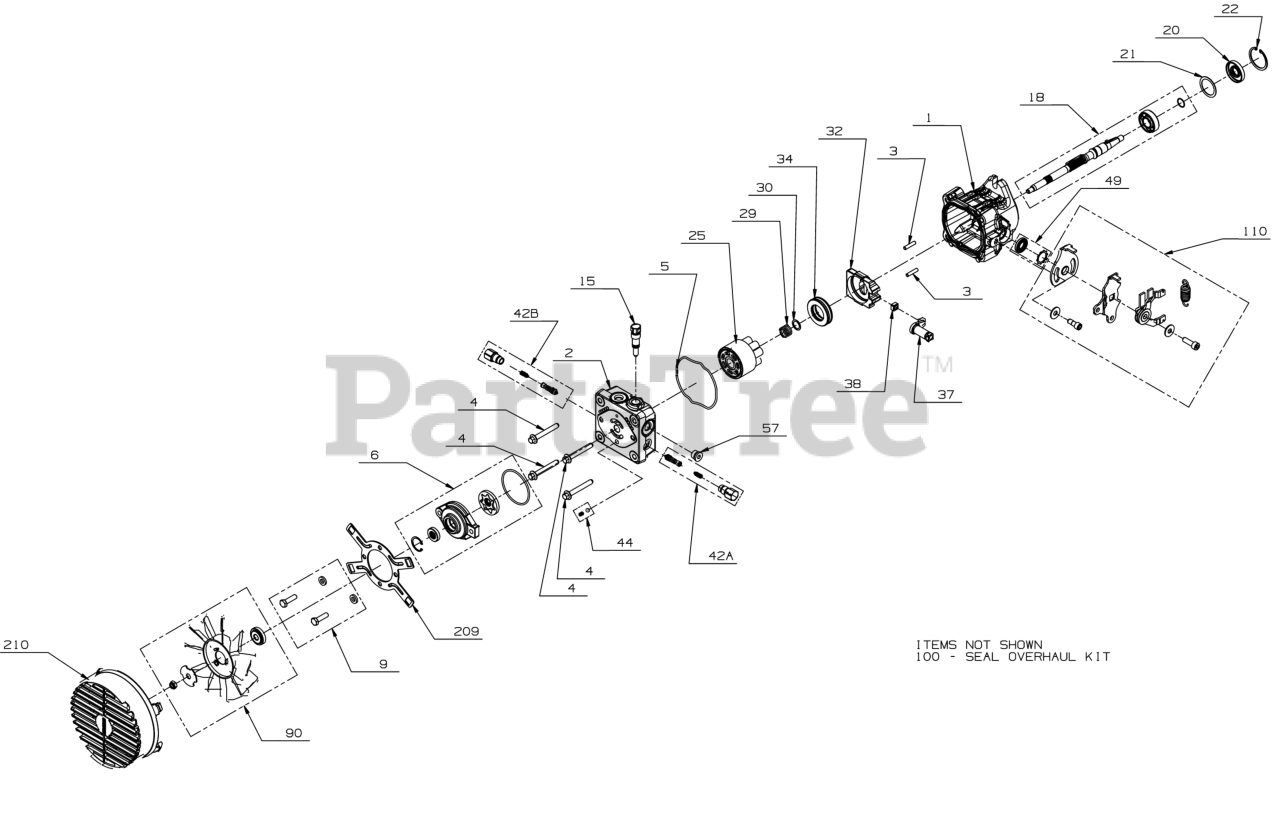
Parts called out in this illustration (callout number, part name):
1	KIT, HOUSING
4	SCREW-FLANGE HEAD
5	O-RING PMP HOUSING
6	PUMP ASSEMBLY-CHARGE
9	BOLT KIT-CHARGE PU
15	VALVE KIT-BYPASS
18	SHAFT KIT-PUMP
21	WASHER 1.23X1.56X
22	RETAINING RING
25	BLOCK KIT-CYLINDER
29	SPRING-BLOCK
30	THRUST WASHER
32	SWASHPLATE, 10cc COATED & SANDED
34	THRUST BEARING
37	ARM-TRUNNION
42A	KIT-SHOCK VALVE
42B	KIT-SHOCK VALVE
44	RELIEF KIT-CHARGE
49	SEAL KIT-TRUNNION
57	PLUG-STRAIGHT THRE
90	FAN KIT-6" 10 BLAD
100	SEAL KIT-OVERHAUL
110	SCISSOR KIT-R T N
209	BRACKET-SHROUD
210	SHROUD, 6 INCH
